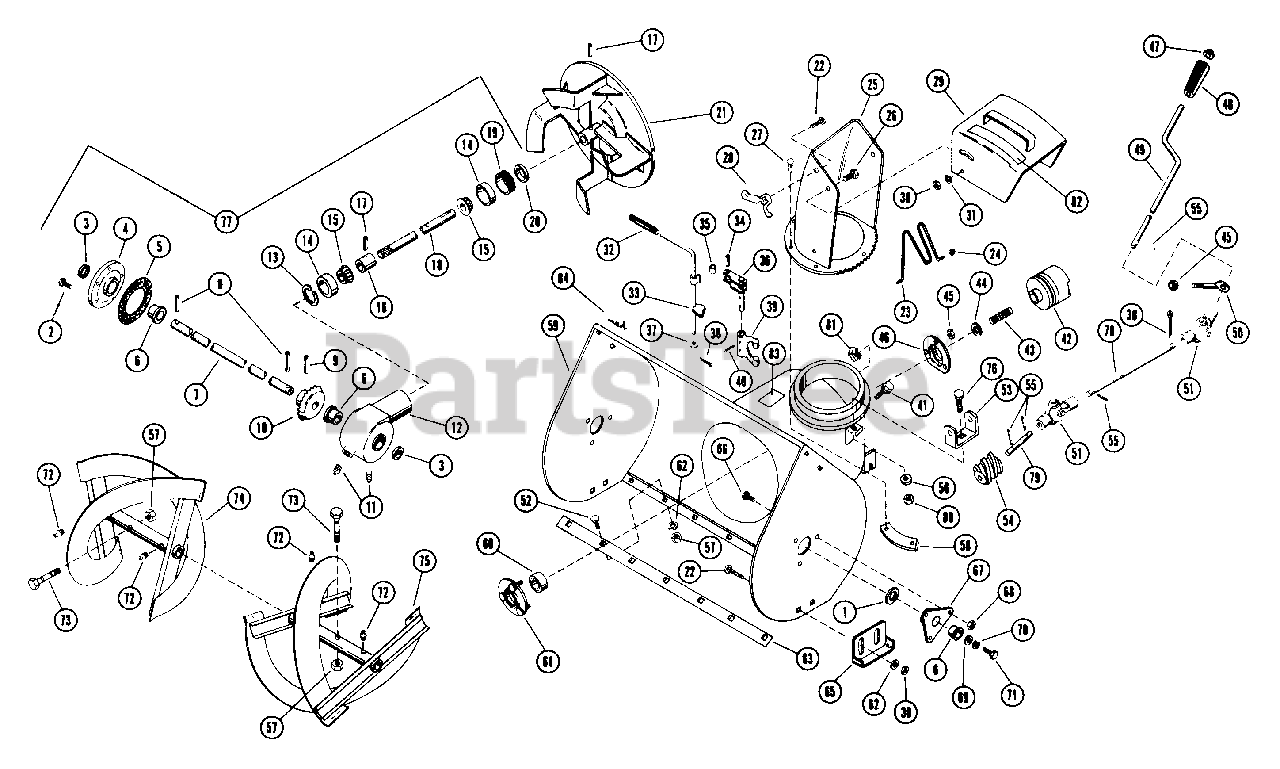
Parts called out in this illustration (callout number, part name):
1	WSHR-FL-STL 1.010X1.505X.062PL
2	BLT-SERHFWH .25-20X.75 PL
3	SEAL 1.000X1.312X.150
4	GEAR CASE FLANGE
6	BSHG-FLG 1.000X1.12X.62X1.50BR
7	FRONT GEAR SHAFT
8	PIN-ROLL .188X1.50
9	PIN-ROLL .313X1.38
10	HELICON GEAR - 41 TOOTH
11	PIPE PLUG
12	CASE, GEAR - C.I.
13	RG-RTNG INT 1.781 HSG X.062
14	BRG-CUP 1.781X.475
15	BRG-CONE .750X.61
16	HELICON PINION SHAFT
17	PIN-ROLL .250X1.25
18	HELICON PINION SHAFT
19	ADJUSTMENT PLUG
20	SEAL .750X1.499X.225
22	BLT-RDHDSQNK .38-16X.75 SHT PL
23	SAFETY WIRE
24	FASTENER
25	DISCHARGE CHUTE
26	BLT-HEX .38-16X.75 PL GR2
27	SCR-TAP 10-24X.375 CRPH 1A
28	WING NUT
29	SERVICE DEFLECTOR ASSM
30	NUT-LK-CTR .375-16 GR A PL
31	WSHR-LK .375X.115 HVY PL
33	FORK CAM
34	PIN-ROLL .313X1.25
36	FORK SHAFT
37	WAVE WASHER .406X.750X.063FH
38	PIN-COTR .12X1.0 PL
39	CLUTCH FORK
40	PIN-ROLL .188X1.00
41	BLT-SCRHFWH .38-16X.75 PL
42	JAW CLUTCH
43	SG-COMP .105X1.35X1.984
44	WSHR-FL-STL .755X1.375X.062 PL
45	NUT-LK-CTR .250-20 PL
46	BEARING FLANGE
47	CAP, 3/8 ROD YWZC
48	GRIP
49	CHUTE CONTROL CRANK
50	ROD HANGER EYEBOLT
51	UNIVERSAL JOINT ASSEMBLY
52	BLT-RDHDSQNK .312-18X.62 PL
53	WORM CLEVIS
54	WORM GEAR
55	PIN-ROLL .125X.75
56	WSHR-LK .313X.062
57	NUT-LK .312-18 GR A PL
58	CHUTE CLAMP
59	SERVICE BLOWER HOUSING ASSM
60	BRG-BALL .750X1.750X.50
61	BEARING FLANGE
62	WSHR-FL-STL .38X.875X.083 PL
63	SCRAPER BLADE
63	SCRAPER BLADE 24"
65	RUNNER
66	SCR-SLTR-SERNK .25-20X.62 PL
67	BEARING SUPPORT
68	NUT-LK-FLG .250-20 PL
69	WSHR-FL-STL .511X1.441X.125 PL
70	WSHR-LK .500X.151 HVY PL
71	BLT-HEX .50-13X1.00 PL GR2
72	SPIN DRIVE ZERK FITTING
73	SHEAR BOLT YWZC
74	RAKE, R.H. - 32"
74	RAKE, RIGHT-24"(1ID X 15.88OD)
75	RAKE, L.H. - 32"
75	RAKE, LEFT-24"(1"ID X 15.88OD)
76	BLT-RDHDSQNK .31-18X.75 GR5 PL
77	GEAR CASE - C.I.
77	GEAR CASE ASSEMBLY
78	ROD
79	WORM SHAFT
80	NUT-HEX .312-18
81	NUT-RETNR .38-16 TINRMAN
82	CAUTION LABEL
83	CLUTCH INSTRUCTION DECAL
84	ARIENS NAME PLATE
